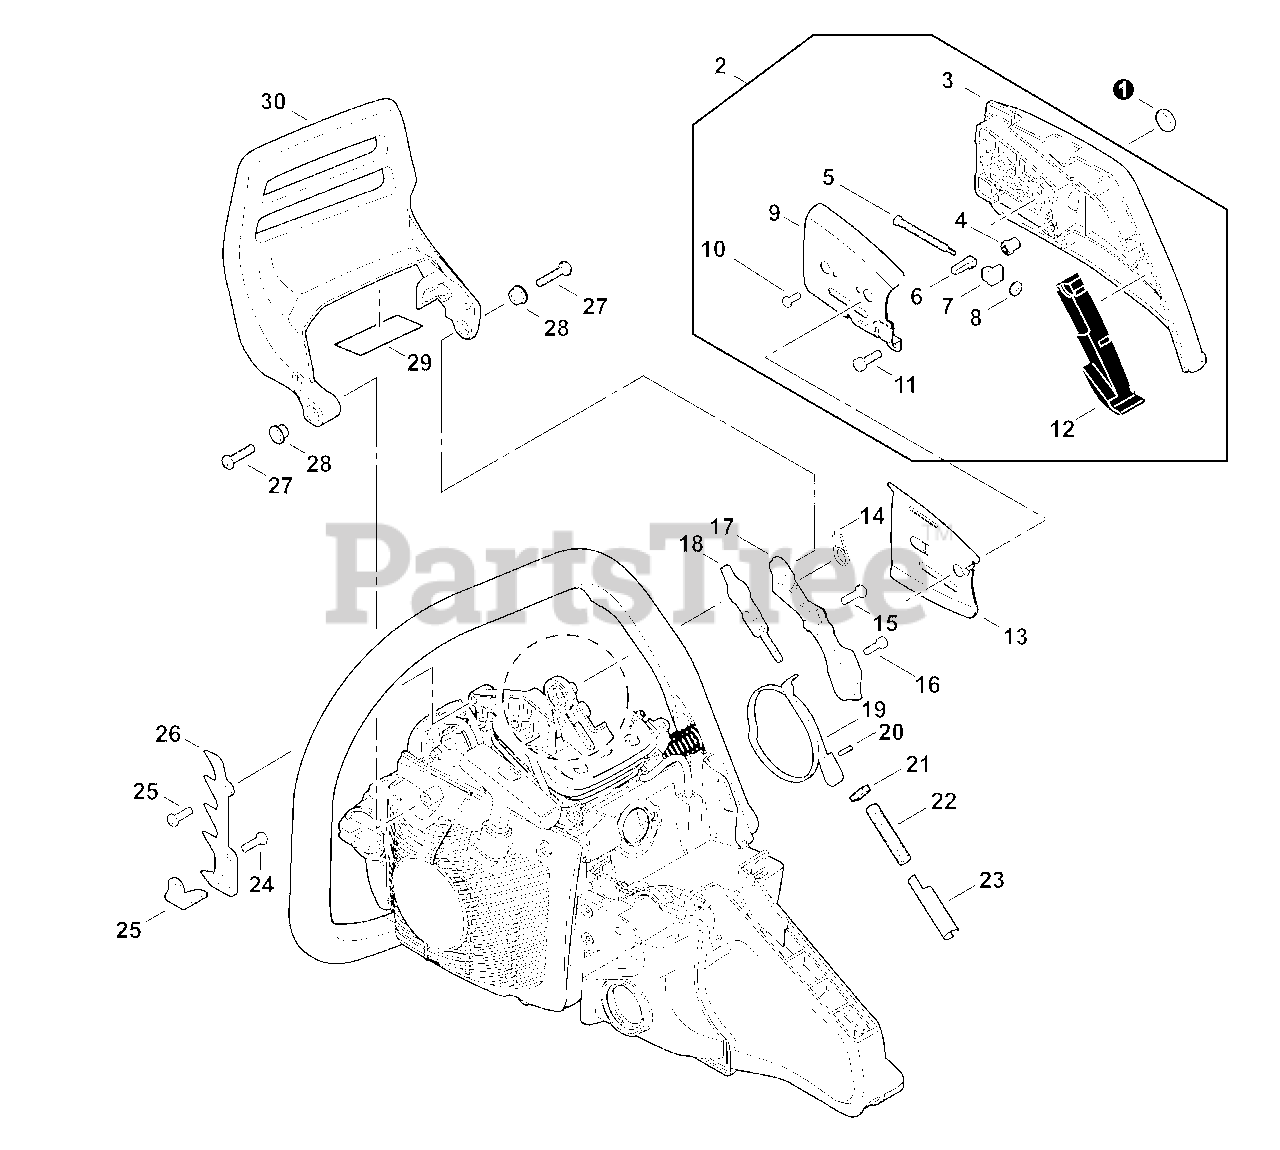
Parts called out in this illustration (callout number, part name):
2	GUARD KIT, SPROCKET
3	GUARD, SPROCKET
4	GEAR, BEVEL
5	SCREW, CHAIN TENSION 63 MM
6	TENSIONER, CHAIN
7	COLLAR 8
8	GEAR, BEVEL
9	PLATE, GUIDE - OUTER
10	SCREW 3×6
11	BOLT, TORX 4×12
12	CUSHION
13	PLATE, GUIDE - INNER
14	SPRING, TORSION
15	BOLT, TORX 5×16
16	BOLT, TORX 4×12
17	COVER, BRAKE
18	CONNECTOR, BRAKE
19	BAND, BRAKE
20	PIN, SPRING 3×9.8
22	SPRING, COMPRESSION 12×70.5
23	PLATE, SIDE
24	BOLT, TORX 5×16
25	CHAIN CATCHER
26	SPIKE, BUMPER
27	BOLT, TORX 5×16
28	COLLAR 11.2×16.2×T0.6
29	SHIELD, HEAT 75×27×0.15
30	LEVER, BRAKE
